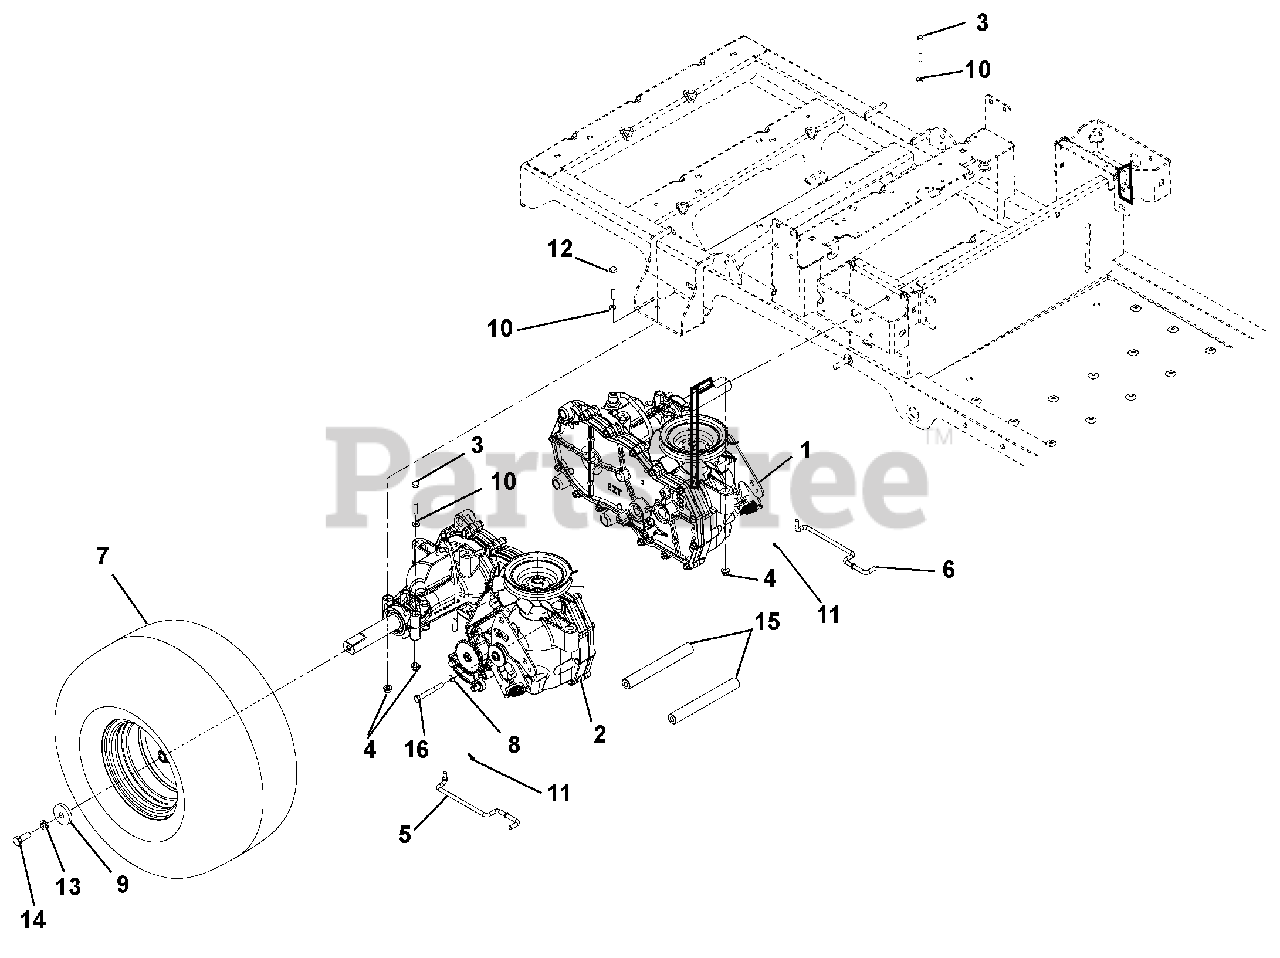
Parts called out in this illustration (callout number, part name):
1	Transaxle, Left Hand EZT D-Shaft (915327)
1	Transaxle, Left Hand EZT D-Shaft Long (915328)
2	Transaxle, Right Hand EZT D-Shaft (915327)
2	Transaxle, Right Hand EZT D-Shaft Long (915328)
3	Bolt, Hex .31-18 x 2.25
4	Nut 5/16-18 Flange Nyloc
5	Dump Valve, Right Hand
6	Dump Valve, Left Hand
7	Tire Assembly 18 x 6.5-8 2 Ply DSHAFT (915327)
7	Tire/Wheel Assembly, 18 x 8.5-8 Center (915328)
8	Washer, Flat Steel .406 x 1.00 x .188
9	Washer, Flat Steel .406 x 1.50 x .245
10	Washer, Flat Steel .38 x .875 x .083
11	Pin, Hair, Internal .06 x .18 x .77
12	Bolt, Hex .31-18 x 2.75
13	Washer, Locking .38 x .094 Regular
14	Bolt, Hex .38-16 x 1.00 YWZC EP30
15	Shaft, Transaxle Brace
16	BOLT, HEX .38-16 X 2.50
